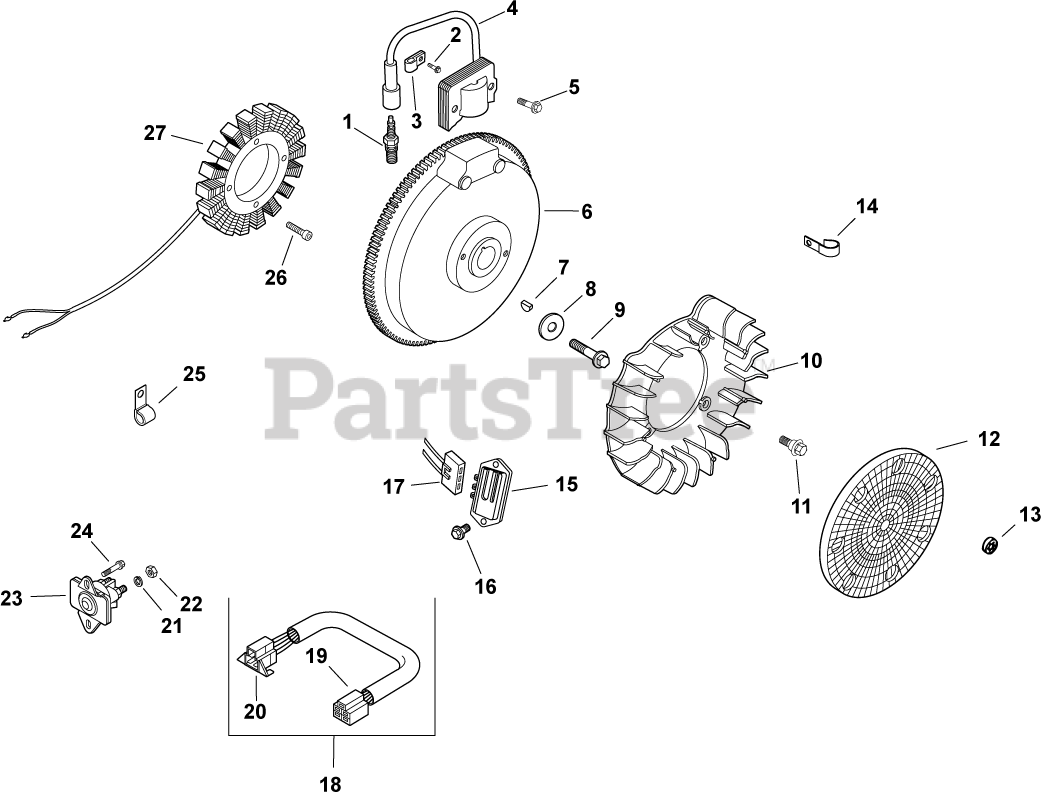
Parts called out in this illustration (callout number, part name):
1	PLUG, SPARK (STD)
2	SCREW, FLG THD FRM M5X.8X10
4	MODULE, IGNITION
5	SCREW, FLG THD FRM M5X.8X20-(#25086399S)
6	FLYWHEEL - USE 12 025 16-S
7	KEY, 3/16" X 5/8"
8	WASHER, FLAT 13/32"
9	SCREW, FLG M10X1.5X45 - (#25086361S)
11	BOLT, SHOULDER
12	SCREEN, GRASS
14	CLIP, CABLE
15	REG/RECT-15 AMP (KM)-USE 41 403 10-S
16	SCREW, FLG M6X1.0X16
17	CONNECTOR, BODY (KM)-USE 25 155 41-S
18	CONNECTOR ASSEMBLY
19	CONNECTOR
20	CONNECTOR
21	WASHER, INT TOOTH LOCK 1/4"
22	NUT, JAM 1/4-20 GRADE 2
23	SOLENOID - WATERPROOF (KM)-USE 25 435 08
24	SCREW,FLG THD FRM M6X1.0X16-(#25086397S)
25	CLIP, TUBE & WIRING (KM)
26	SCREW, M5X0.8X25 - (#25086402S)
27	KIT, 15 / 20 AMP STATOR
